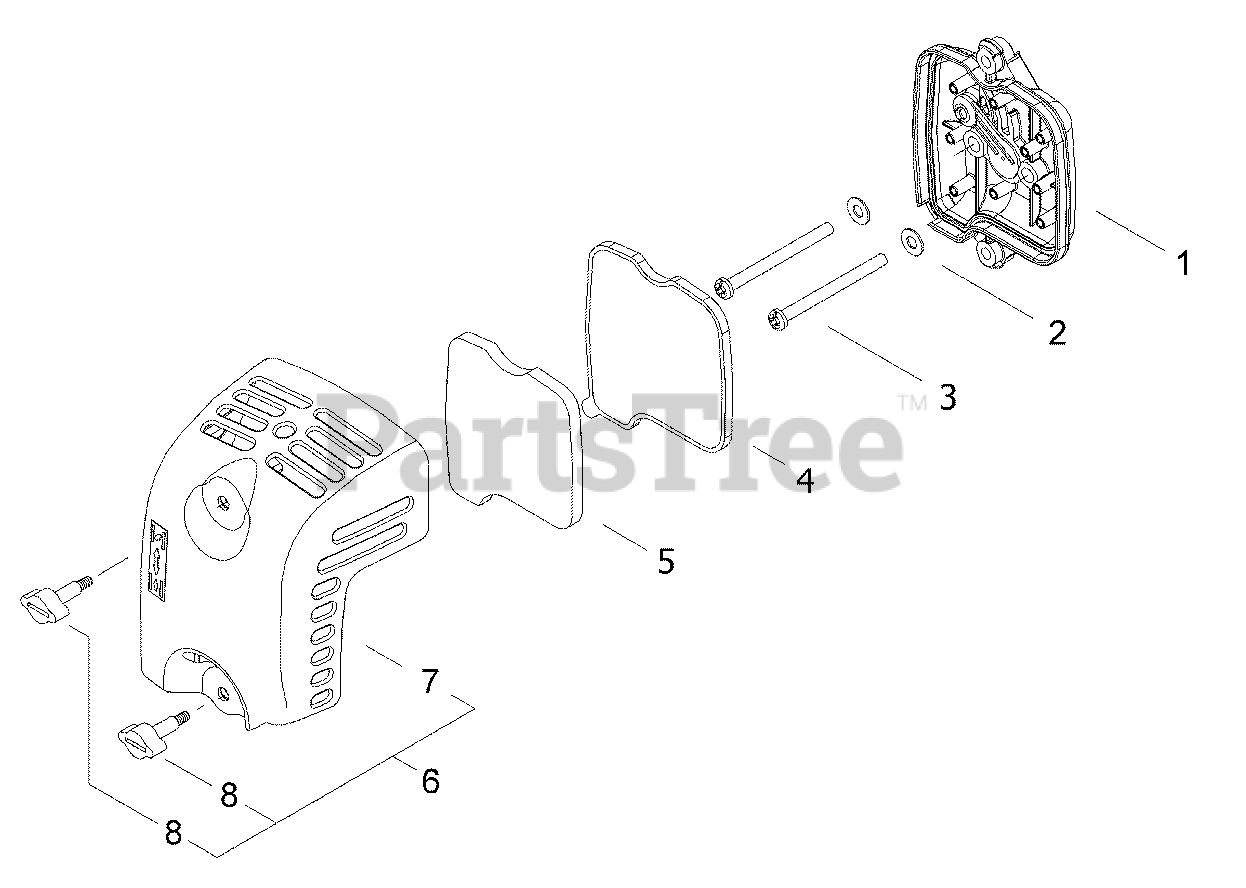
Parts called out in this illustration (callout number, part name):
1	CASE ASSY, AIR FILTER
2	WASHER 5 MM
3	SCREW M5×60
4	FILTER, AIR
5	PRE-FILTER, FOAM
6	COVER ASSY, AIR FILTER
7	COVER, AIR FILTER
8	THUMBSCREW M5
